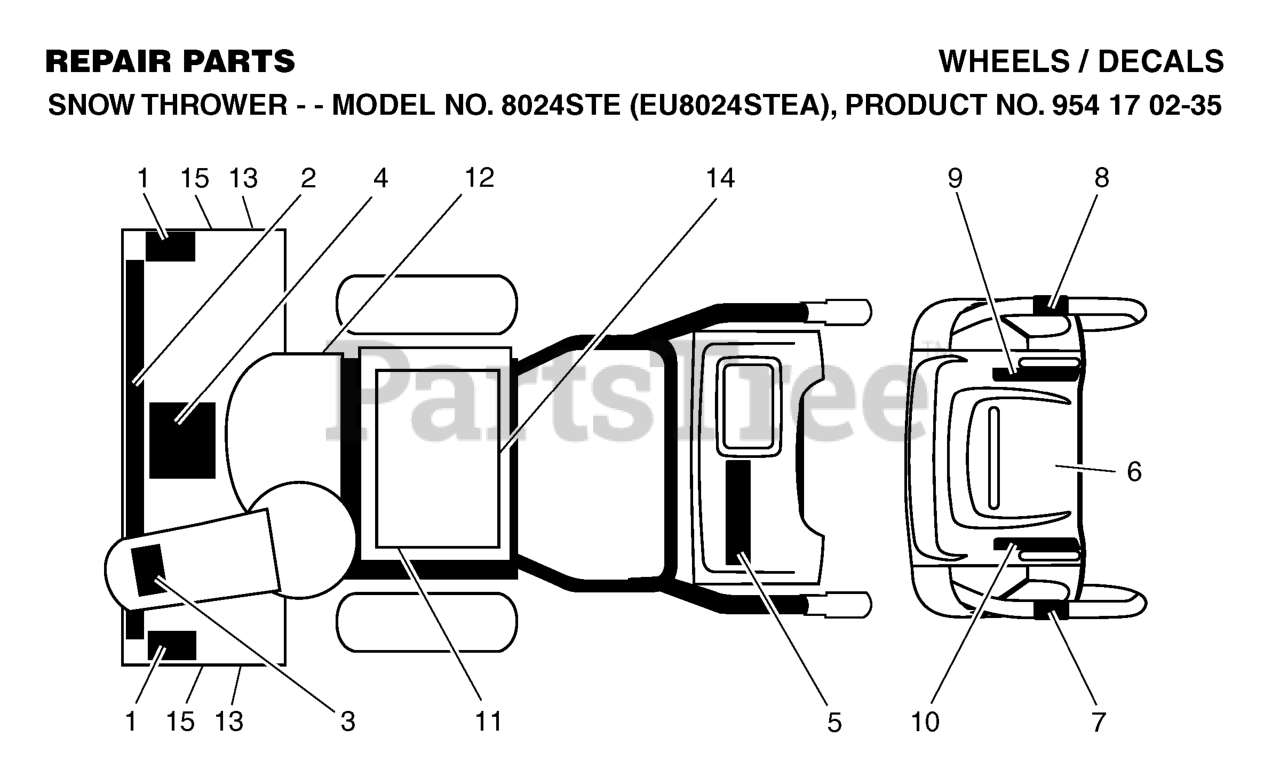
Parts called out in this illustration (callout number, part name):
2	DECAL.AUGER.HSG.24"
4	DECAL.AUGER."
6	DECAL.CONSOLE.INSTRUCTION
10	DECAL.REM.DEFLECTOR.LT
12	DECAL.BELT.GUARD.
14	DECAL.FENDER
15	DECAL, HUSQVARNA
